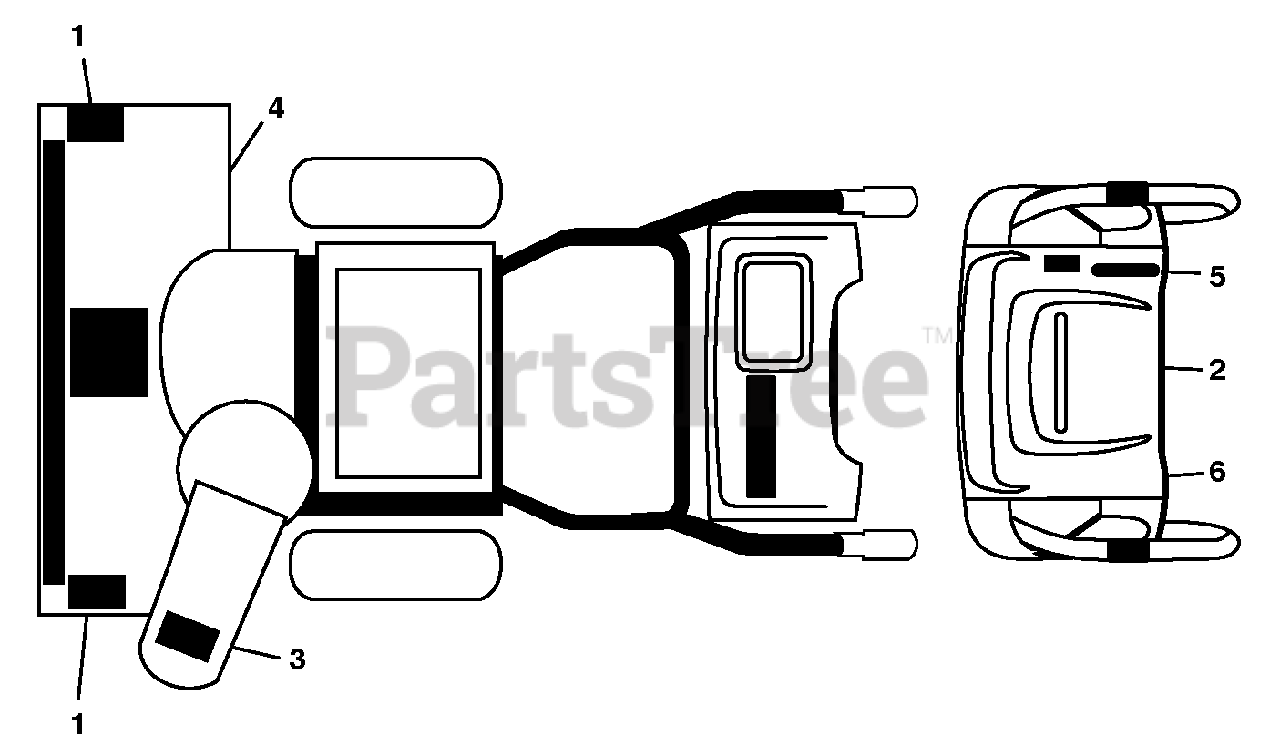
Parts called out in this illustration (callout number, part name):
1	DECAL.SNOWTHR.AUGER
2	Instruction Panel Decal
3	Decal, Snow Thrower Chute Safety
4	Decal, Snow Thrower Read Owner's Manual E/F
5	DECAL.CONS.RT.SPD/LEV/P.WRST
6	DECAL.CONS.LT.SPD/LEV/P.WRST
